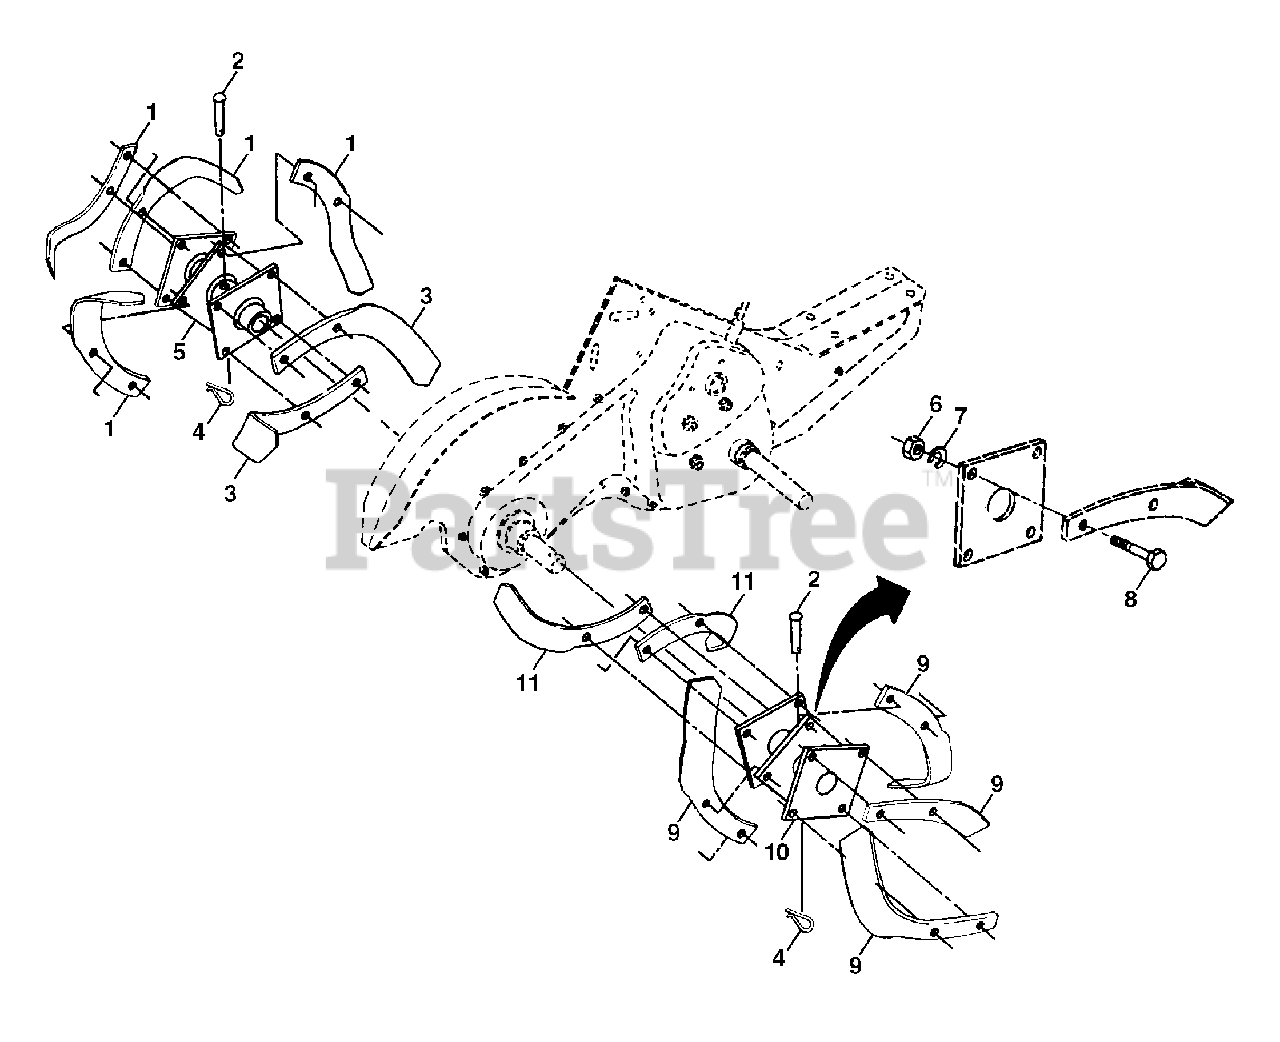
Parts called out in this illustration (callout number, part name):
1	Tine, Outer, L.H.
2	Clevis Pin
3	Tine, Inner, L.H.
4	Retainer, Spring
5	Assembly, Hub and Plate, L.H.
6	Nut, Hex 3/8-24
7	Washer, Lock 3/8
8	Bolt, Hex 3/8-24 x 1
9	Tine, Outer, R.H.
10	Assembly, Hub and Plate, R.H.
11	Tine, Inner, R.H.
